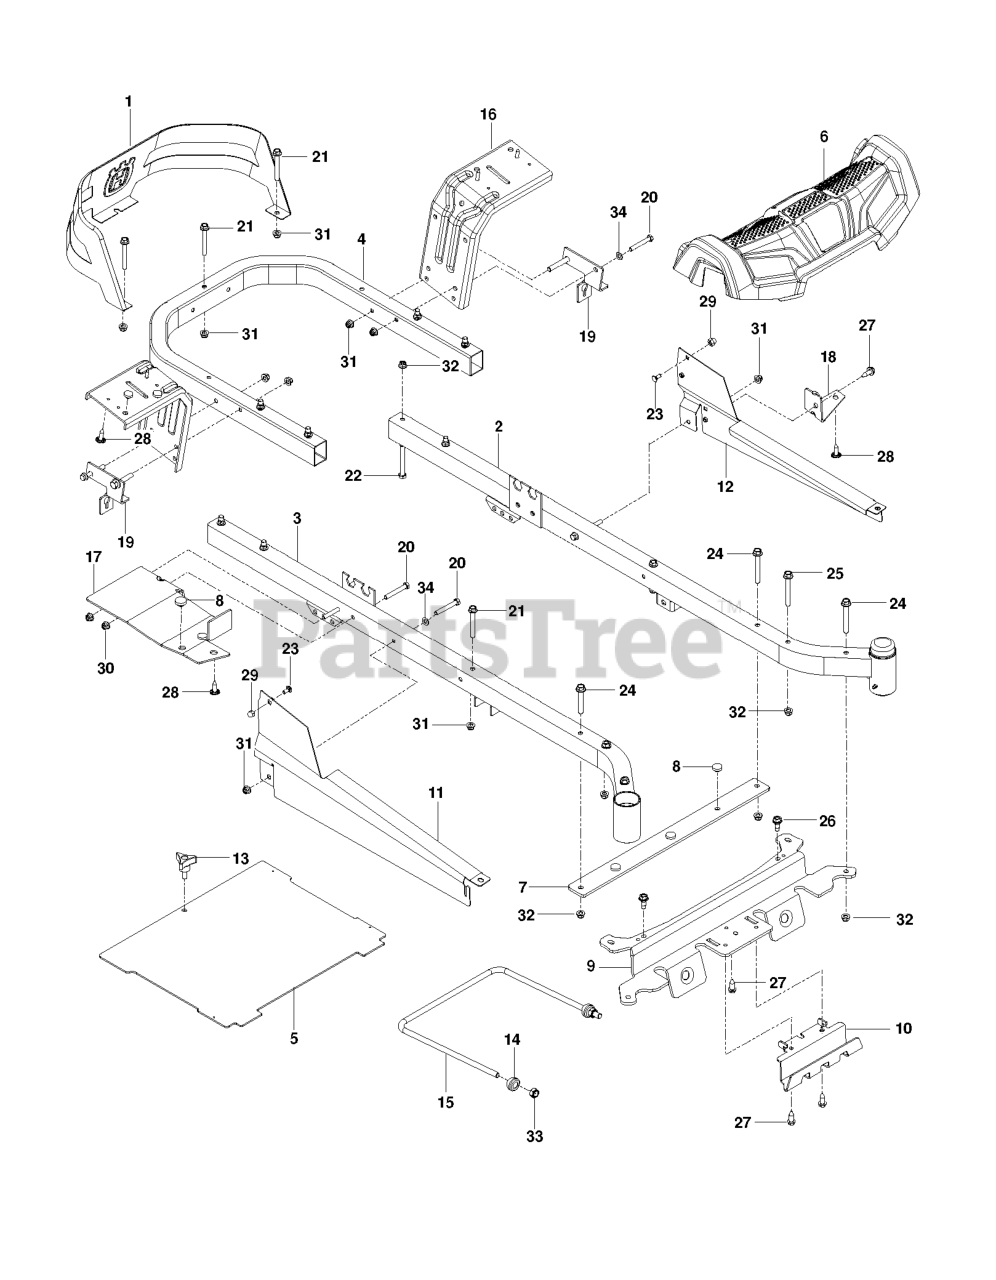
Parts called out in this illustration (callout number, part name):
1	GUARD.ENGINE.HUSQ.RZ.X498
2	FRAME, RT, ORANGE
3	FRAME, LT, ORANGE
4	TUBE.PNT.FRAME.RER.HUSQ.23".RZ
5	PLATE, FOOT W/DECALS RZ
6	FRONT COVER RZ REFRESH
7	FOOTREST.PLATE.SUPPORT.X431
8	GROMMET.BUMPER
9	CROSS.PNT.MEMBER.BLK
10	SKID.PLATE.PNT.RZ.REF.SIVER
11	COVER.RAIL.RH.RZ.X668
12	COVER.RAIL.LH.RZ.X668
13	KNOB W/STUD
14	BUSHING SPHERICAL SUSP. FRONT
15	LINK, FRONT SUSP.
16	FENDER.SUPPORT.PNT.X431
17	SUPPORT.PNT.RH.CONSOLE.FRONT
18	SUPPORT.PNT.LH.CONSOLE.FRONT
19	BRKT ROD.BYPASS.EZT.X431
20	BOLT.FIN HEX 5/16-18UNC X2 1/4
21	BOLT HEX
22	BOLT.HEX.FIN.3/8-16 X 3.GR5
23	BOLT.CARRIAGE.5/16-18.7/16
24	HHFS 3/8-16 X 3 GRD 5 ZD
25	BOLT SHOULDER,FLANGED,3/8-16X3
26	BOLT.5/16-18.THRD.ROLL.SHOULDR
27	BOLT.5/16HEX.WHS.HD
28	SCREW.#10 X 0.750.BOS
29	NUT ACORN,FLANGED,5/16-18
30	NUT LOCK HEX FLANGE 5/16-18
31	5/16-18 NYLOC FLANGE NUT
32	NUT 3/8-16 HEX FLG NYLOC ZD
33	7/16-14 HEX NUT W/NYL RING ZD
34	WASHER - 15X7.3X1.6
